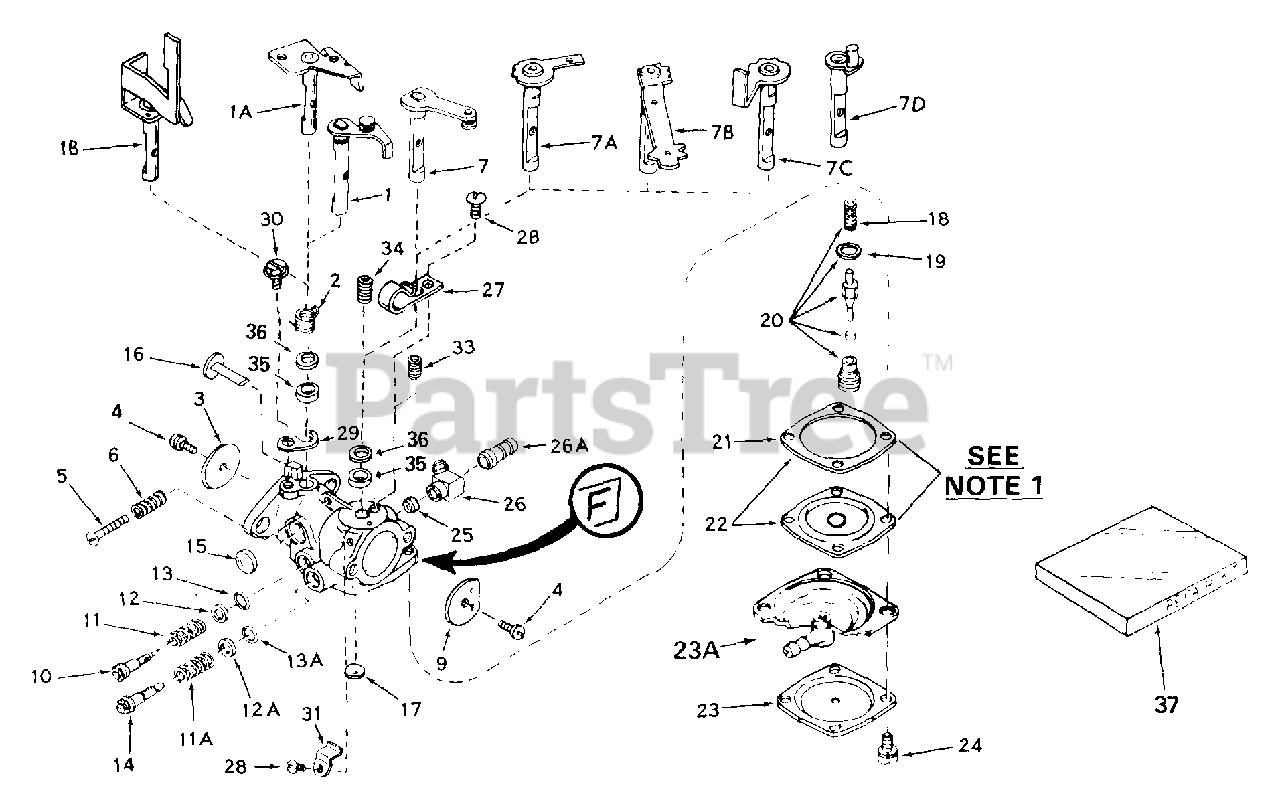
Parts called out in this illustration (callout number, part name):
1A	"Shaft & Lever Assy., Throttle
2	Spring, Throttle return
3	Shutter, Throttle
4	Screw, Shutter
5	Screw, Idle regulating
6	Spring, Idle regulating screw
7C	Shaft & Lever Assy., Choke
9	Shutter, Choke
10	Screw, Idle adj.
11	Spring, Idle adj. screw
11A	Spring, Main adj. screw
12	Washer, Idle adj. screw
12A	Washer, Main adj. screw
13	"O" Ring, Idle adj. screw
13A	"O" Ring, Idle adj. screw
14	Screw, Main adj. (.0225 dia. hole)
15	Plug, Welch
16	Element, Pump
17	Plug, Welch
18	Spring, Valve
19	Gasket, Valve seat
20	Inlet Needle, Seat, Gasket & Spring A ssy.
21	Gasket, Diaphragm
22	Diaphragm Assy.
23	Cover, Diaphragm
24	Screw, Cover
25	Valve, Check
26	Fitting, Fuel inlet
27	Spring, Detent
29	Retainer, Throttle shaft
37	Repair Kit
